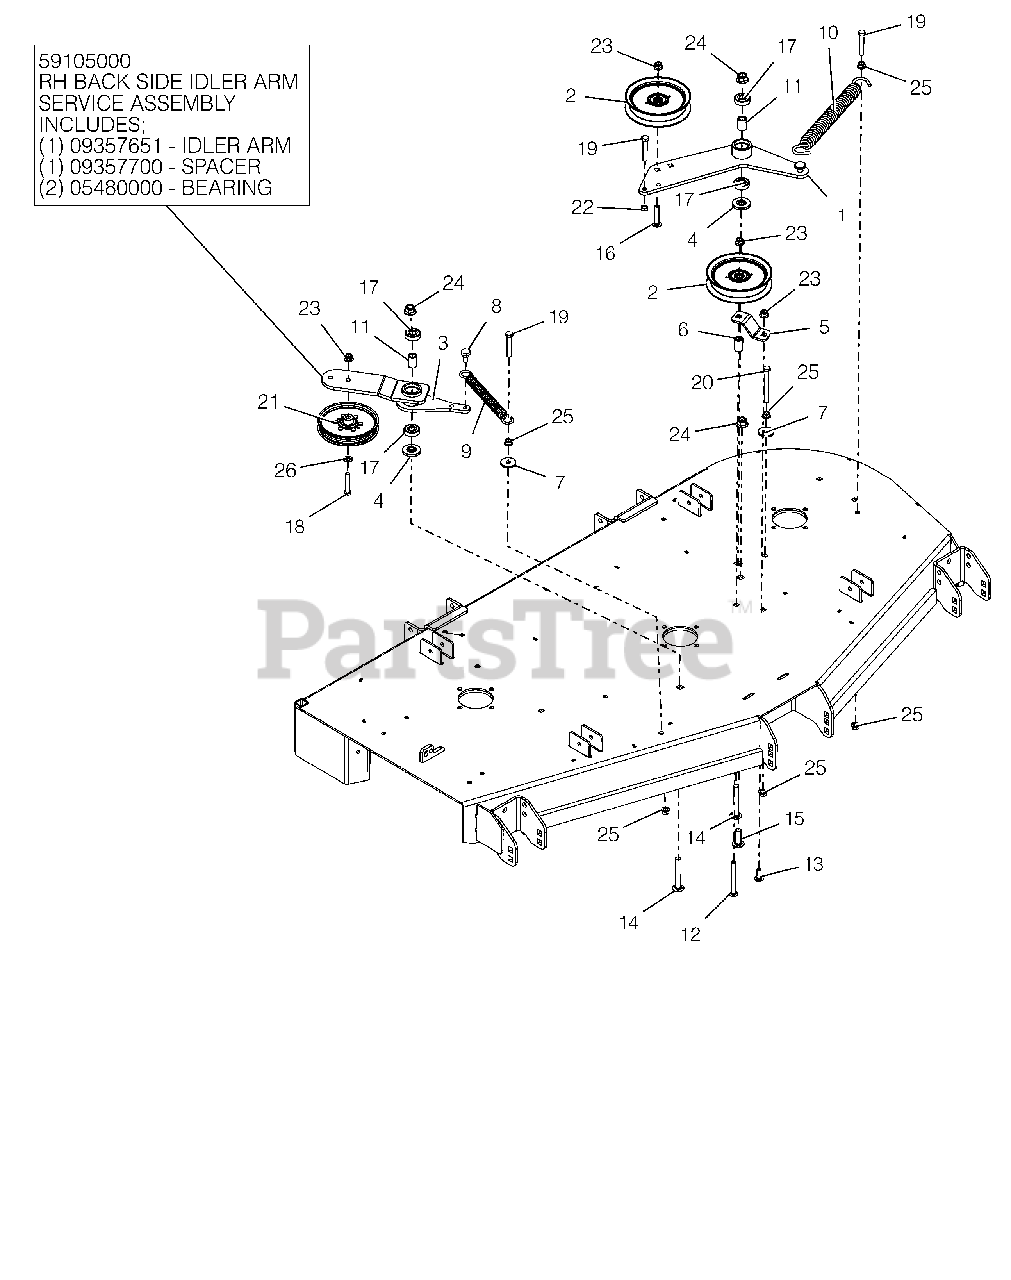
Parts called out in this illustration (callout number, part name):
1	DECK PTO IDLER ARM WLDMT - BLK
2	IDLER, FLAT 5.00"
3	DECK RH IDLER ARM WMT - BLK
3	RH BACKSIDE IDLER ARM ASSEMBLY
3	SPACER .510 X .75 X 1.1485
3	BRG-BALL .50X1.38X.438 SEALED
4	SPACER, IDLER ARM
5	PTO FIXED IDLER MTG BRKT -RED
6	BUSHING, SLV .380X.750X1.190
7	WSHR-FL-STL .406X1.375X.135 YZ
8	BLT,SHLDR EP .38-16X.30 HEX YZ
9	SPRING, EXTENSION
10	SPRING, EXTENSION
11	SPACER .510 X .75 X 1.1485
12	@BLT-RHDSSQNK .38-16X3.50 G5YZ
13	@BLT-RDHDSHSQNK.38-16X1.0 G5YZ
14	BLT,RDHDSQSHNK.50-13X3.25 G5YZ
15	BLT-RDHDSHSQNKFT.50-13X1.50 G5
16	BLT-RDHDSQNK .38-16X2.00 SHTYW
17	BRG-BALL .500X1.38X.437
18	@BLT-HEX .38-16X2.00 GR5 YWZC
19	@BLT-HEX .38-16X2.25 GR5 YWZC
20	@BLT-HEX .38-16X3.50 GR5 YWZC
21	PULLEY, FLAT IDLER
22	NUT-HEX-JAM .375-16 YWZC
23	@NUT-LK-NYL-FLG .38-16 YWZC
24	@NUT-LK-NYL-FLG .50-13 YWZC
25	@NUT-SPNLK-FLG .375-16 YWZC
26	@WSHR-FL-STL.406X.812X.065 YWZ
